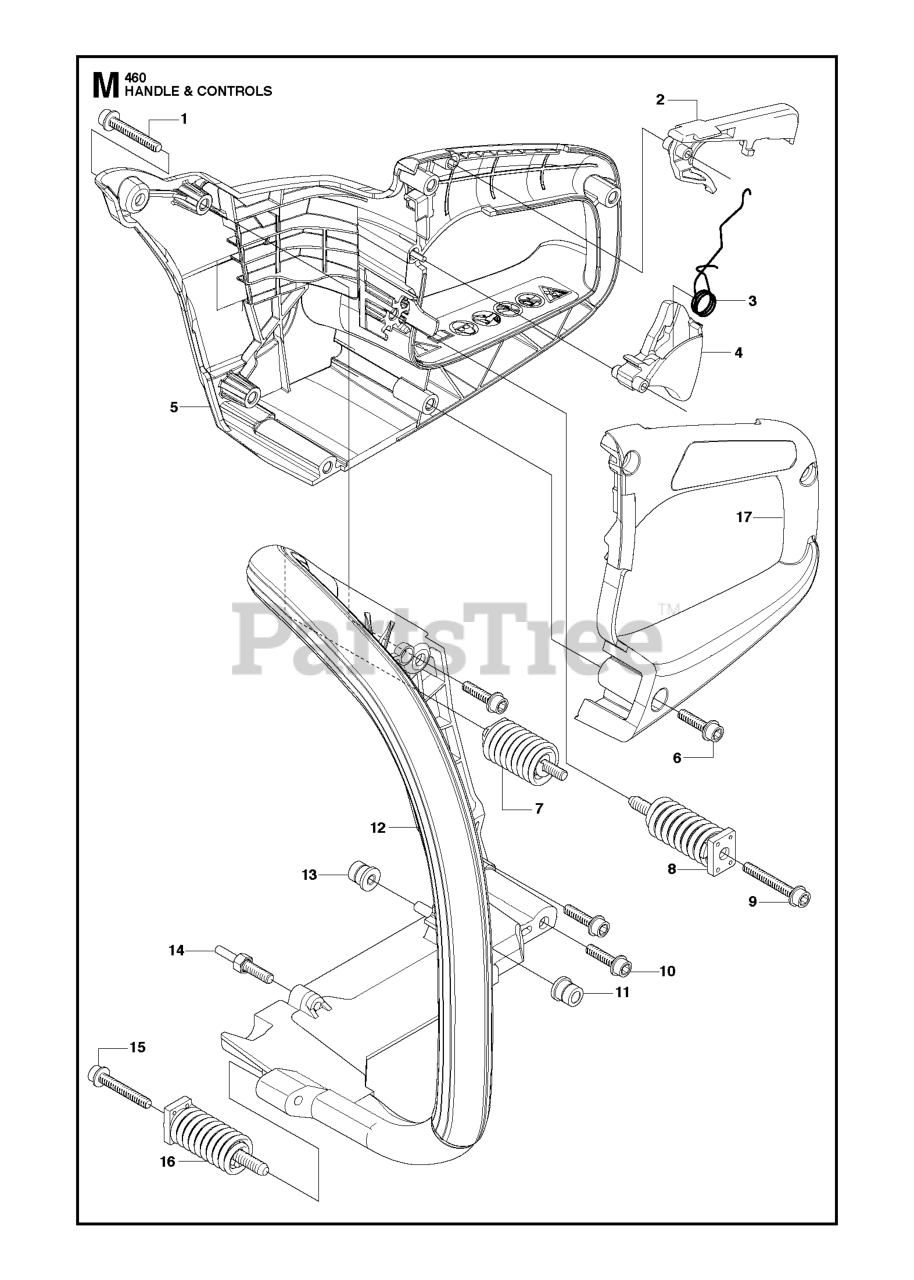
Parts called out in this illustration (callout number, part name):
2	THROTTLE LOCK
4	THROTTLE TRIGGER
5	REAR HANDLE
7	VIBRATIONS ABSORBER
8	VIBRATION ABSORBER
11	MOVEMENT LIMITER
12	FRONT HANDLE
13	MOVEMENT LIMITER
17	CAP - LEFT SIDE HANDLE
